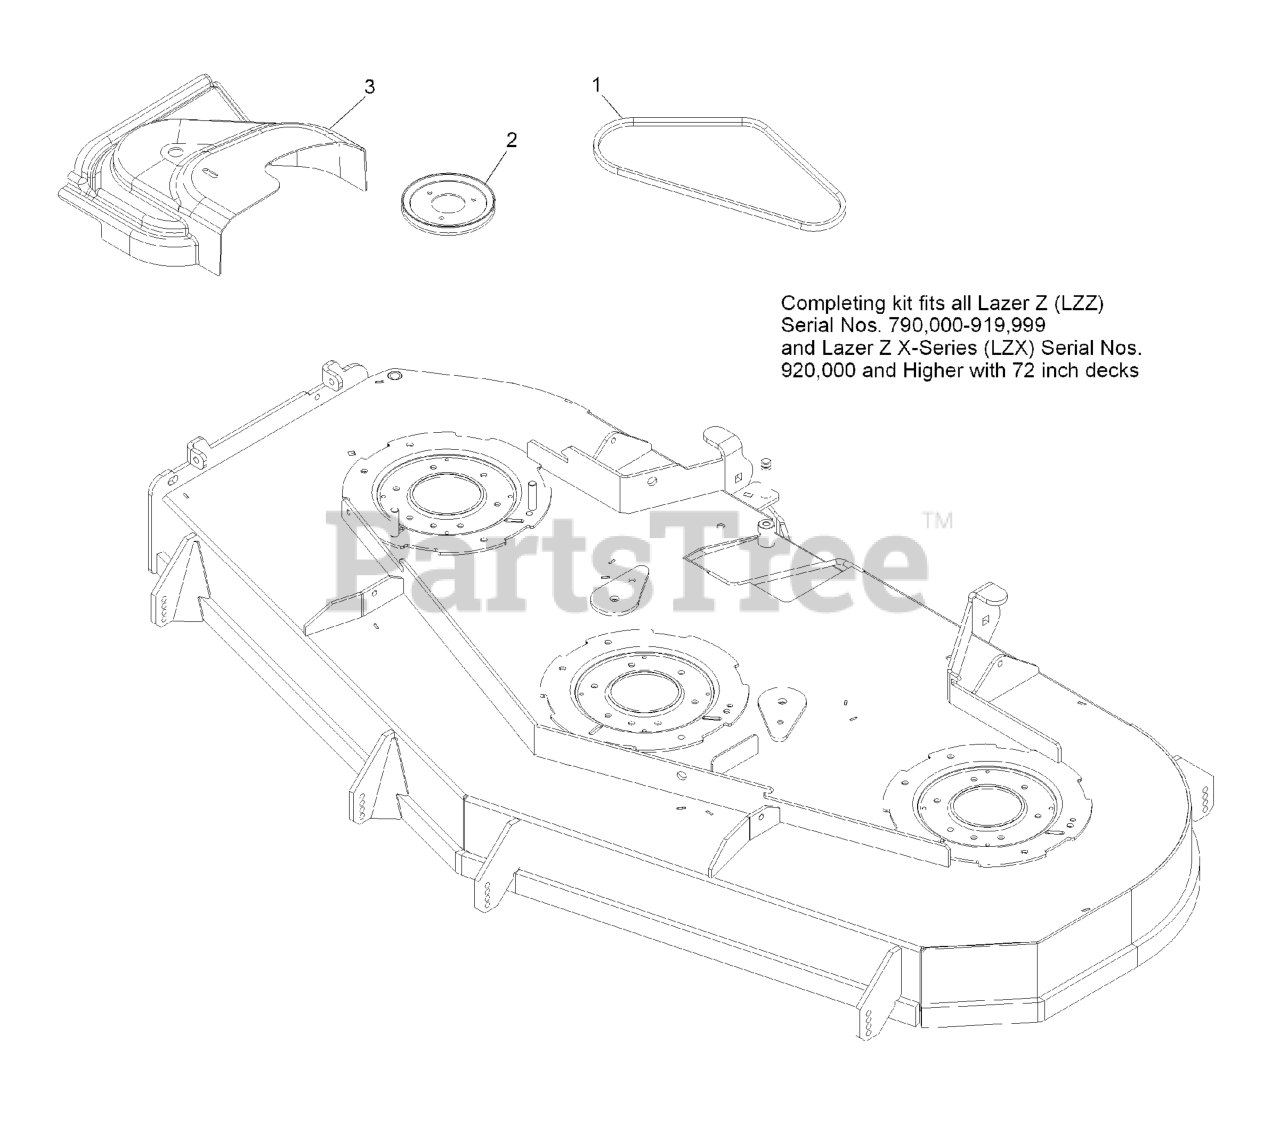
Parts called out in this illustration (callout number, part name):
1	BELT, BLOWER DRIVE 72
2	SHEAVE,DRIVE LZUV 726
3	COVER,BELT UV 72
